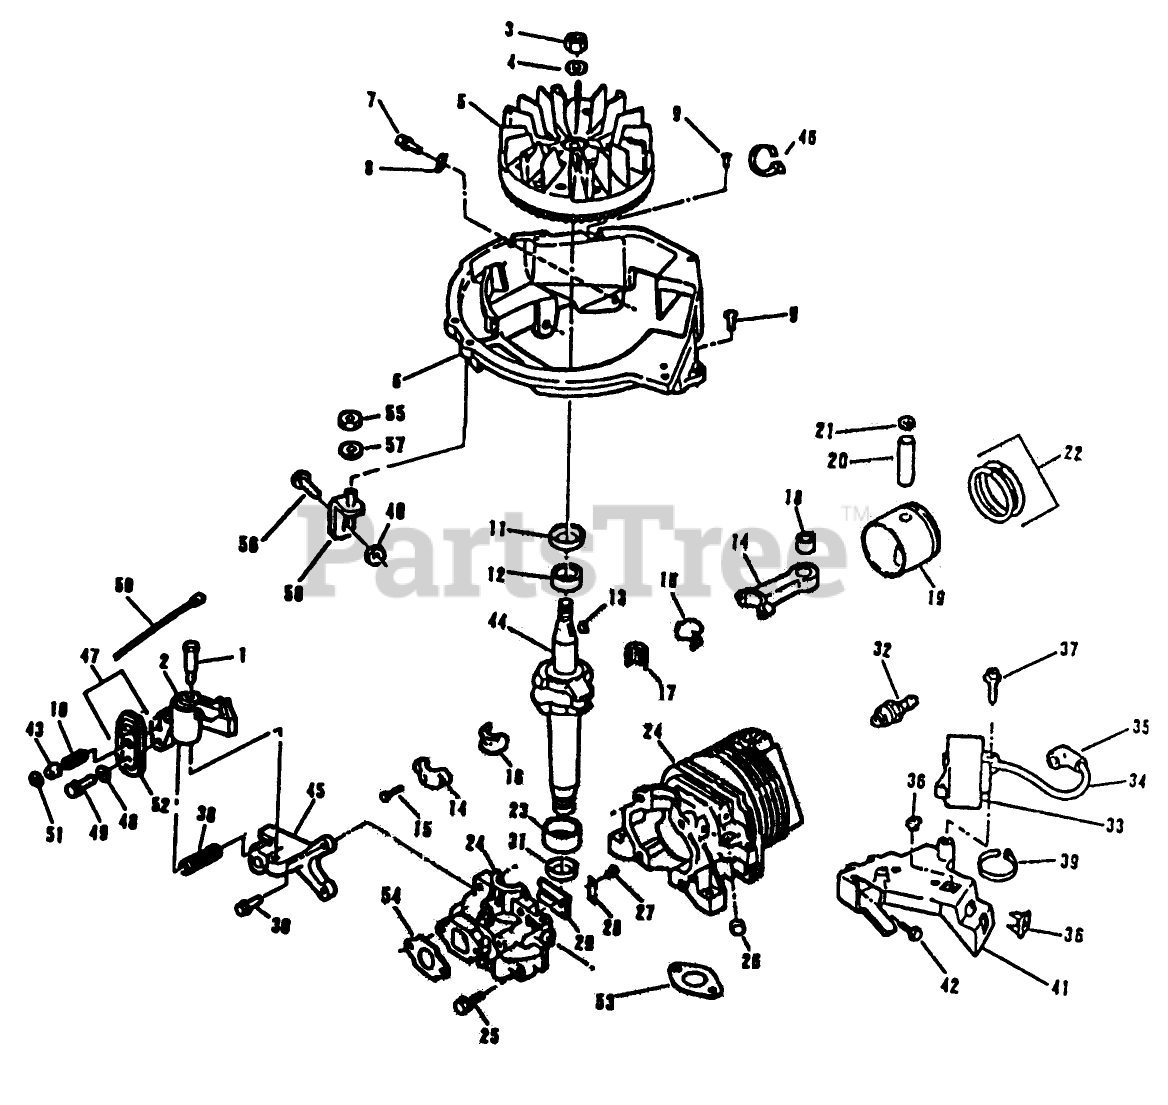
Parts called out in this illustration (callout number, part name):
1	SCREW-SHOULDER
3	NUT
5	FLYWHEEL ASSY F
6	BASE SHROUD F
7	SCREW-SEMS
9	SCREW F
10	SPRING
11	SEAL-OIL
12	BEARING V
13	KEY
15	SCREW-HSH
16	LINER ASM
17	BEARING-NEEDLE
18	BEARING AY F
21	RING-RETAINING
23	BEARING V
25	SCREW-H.W.HD. F
26	PLUG-CORE VF
27	SCREW-HH
28	PLATE-BACKUP, REED
30	SCREW
31	SEAL-OIL
34	HT LEAD&COVER XEV
36	NUT-CLIP
38	SPRING-BRAKE
40	NUT-LOCK F
41	C.D. BRKT F
43	ACTUATOR-LEVER, BRAKE
45	BRACKET-BRAKE F
48	WASHER
50	WIRE LEAD AY F
51	RETAINER S
54	GASKET CARB S
55	LOCKNUT E
56	BOLT F
57	WASHER S
58	BRACE AY F
